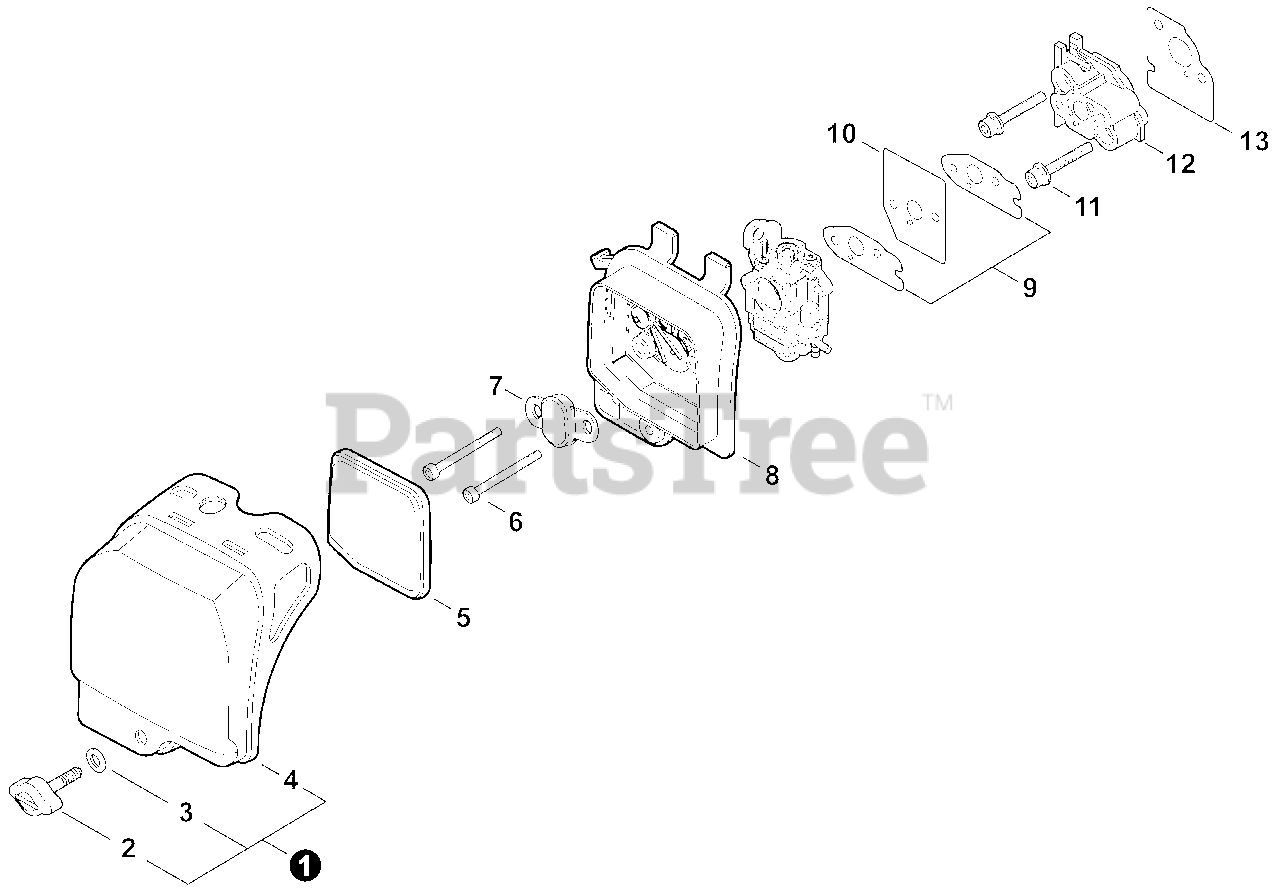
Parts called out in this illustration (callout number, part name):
1	COVER ASSY, AIR FILTER
2	THUMBSCREW
3	WASHER 5
4	COVER, AIR FILTER
5	FILTER, AIR
6	BOLT M5×60
7	BRACKET
8	CASE ASSY, AIR FILTER
9	GASKET, INTAKE
10	HEAT SHIELD, INTAKE
11	BOLT 5×30
12	INSULATOR, INTAKE
13	GASKET, INTAKE
